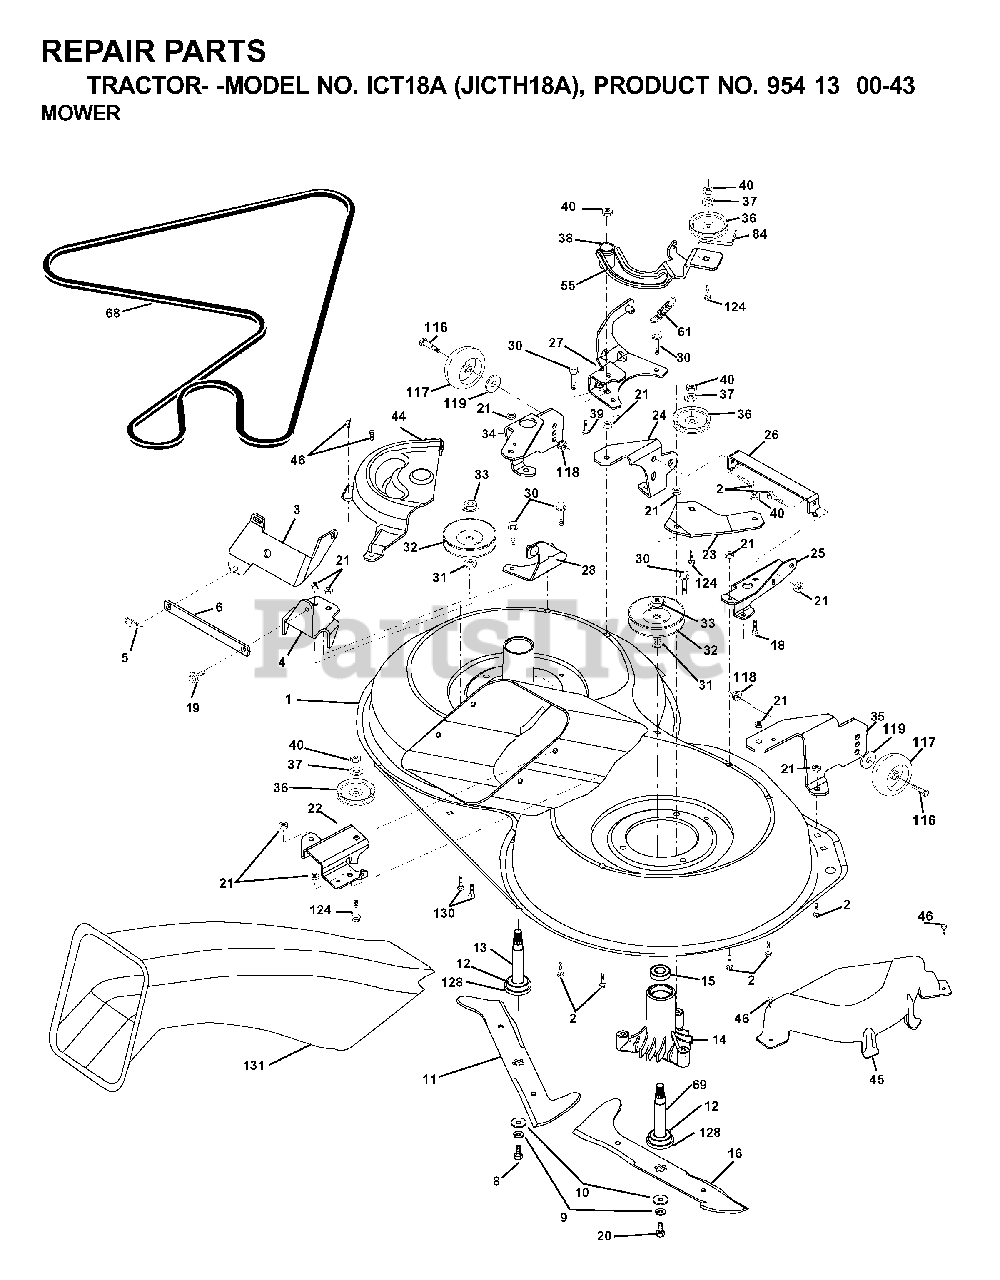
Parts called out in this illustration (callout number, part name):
2	BOLT
3	BRACKET
5	RETAINER-SPRNG RB
6	BAR SWAY
8	BLADE BOLT
9	LOCKWASHER
10	WASHER.BLADE
11	BLADE - LH (CTH150)
12	BEARING
13	SHAFT ASM VENT
14	HSG MANDREL
16	BLADE - RH (CTH150)
19	BOLT SHD 5/16-18
21	LOCKNUT
22	BRACKET
23	BRACKET
26	BRACE
27	BRACKET
30	SCREW THDROL ROLLING WASHER HD
31	WASHER
32	PULLEY/MANDREL
33	NUT
34	BRACKET
36	PULLEY.IDLER.4.25
40	LOCKNUT
45	MANDREL COVER RH
46	SCREW.1/4-20X5/8
55	ARM IDLER
61	SPRING.TENSION.BELT
67	KNOB T (3/8 HOLE)
68	HEX-BELT 107 MOWER
69	SHAFT.ASM.W/LWR.BRG.RH.THREAD
84	KEEPER, BELT IDLER
116	BOLT, SHOULDER
117	WHEEL GAGE DONUT
118	LOCKNUT
119	WASHER
124	BOLT.3/8-16X1.50
128	WASHER FELT
131	CHUTE BAGGER
